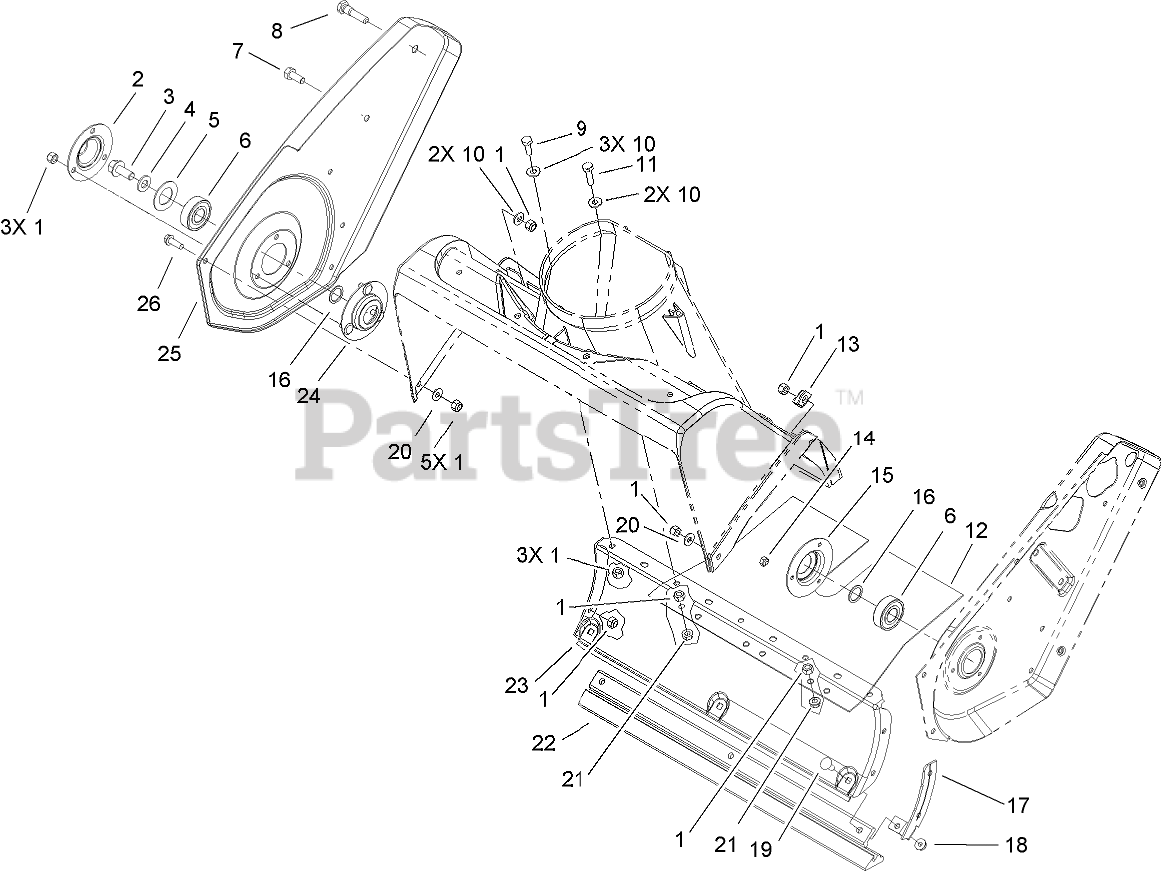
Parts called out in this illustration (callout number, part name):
1	NUT-LOCK, NI
2	RETAINER-BEARING
3	SCREW-HHF
4	WASHER-FLAT
5	WASHER-RUBBER
6	BEARING-BALL
7	SCREW-HH
8	PIN-ROTOR
9	SCREW-HH
10	WASHER-FLAT
11	SCREW-HH
12	COVER-BOTTOM
13	BRACKET-HOUSING
14	NUT-LOCK, NI
15	FLANGE-BEARING
16	WASHER-THRUST
17	BRACKET-HOUSING, LOWER
18	NUT-KEPS
19	SCREW-CARR
20	WASHER-FLAT
21	NUT-LOCK, HHF
22	SCRAPER
23	HOUSING-LOWER
24	FLANGE-BEARING
25	SIDEPLATE-RIGHT
26	SCREW-HWH
